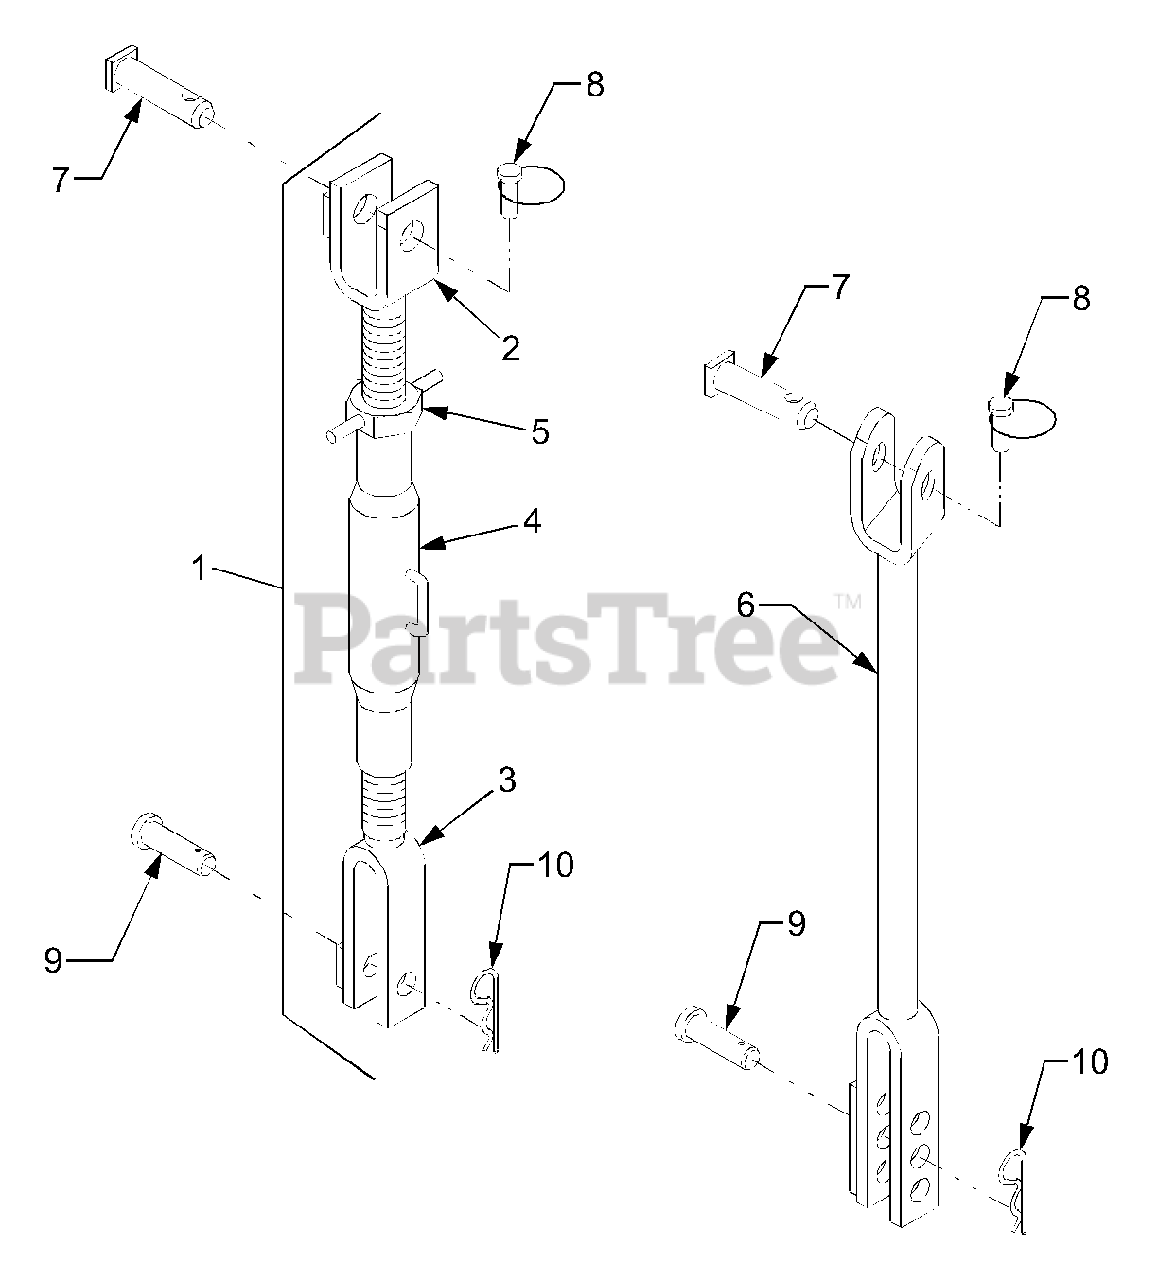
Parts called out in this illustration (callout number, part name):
1	Lift Rod Ass'y (RH)
2	Rod, Lift (Upper)
3	Rod, Lift (Down)
4	Body, Lift Rod
6	Lift Rod Ass'y (LH)
7	Pin, Lift Rod (Upper)
